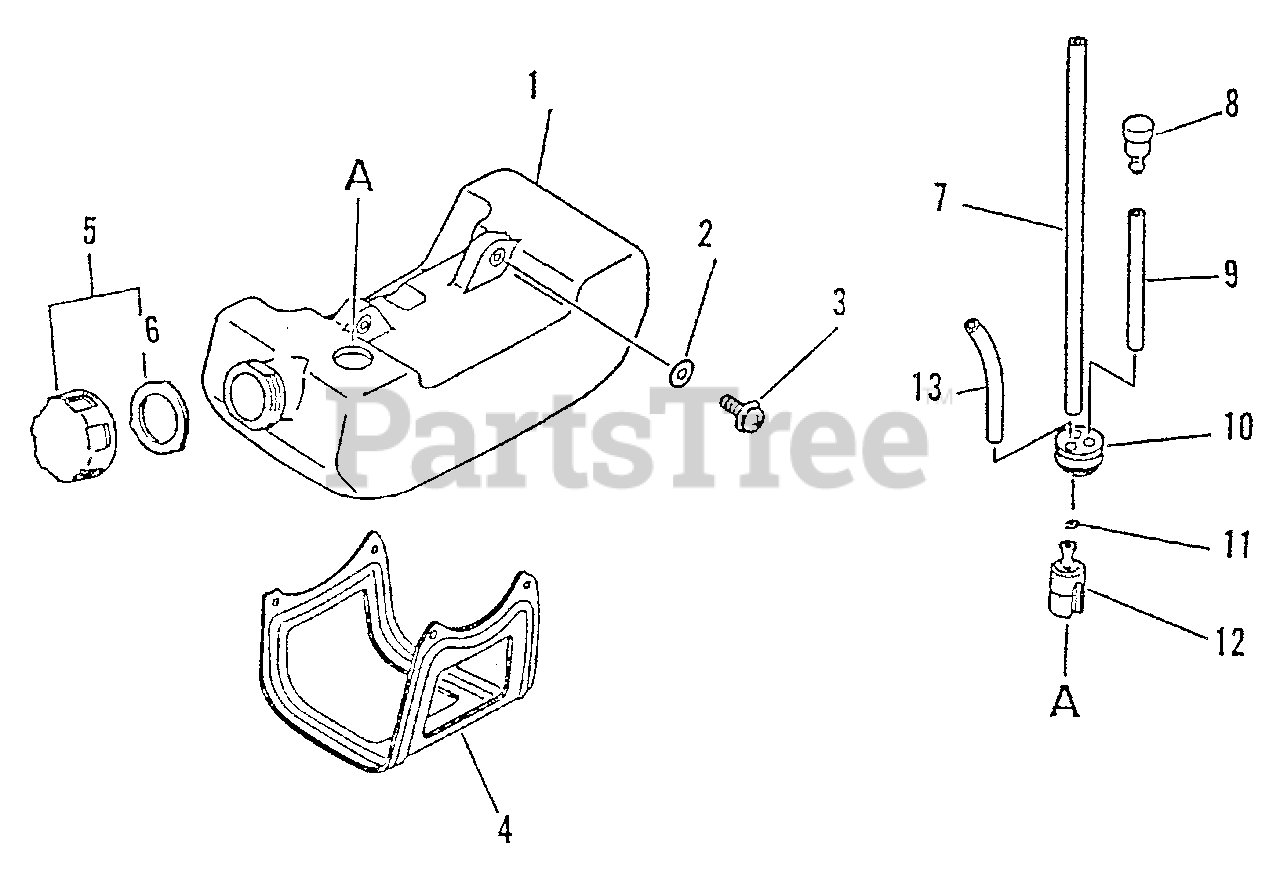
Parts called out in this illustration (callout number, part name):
1	TANK, FUEL
2	WASHER - 5
3	SCREW - 5X16
4	GUARD, FUEL TANK
5	CAP ASSY
6	GASKET, CAP
7	PIPE - 3X5X180 -- BLACK
8	VENT, FUEL TANK
9	PIPE - 3X5X70 -- BLACK
10	GROMMET
11	CLIP - 6
12	FILTER, FUEL
13	PIPE - 3X6X80 -- CLEAR
